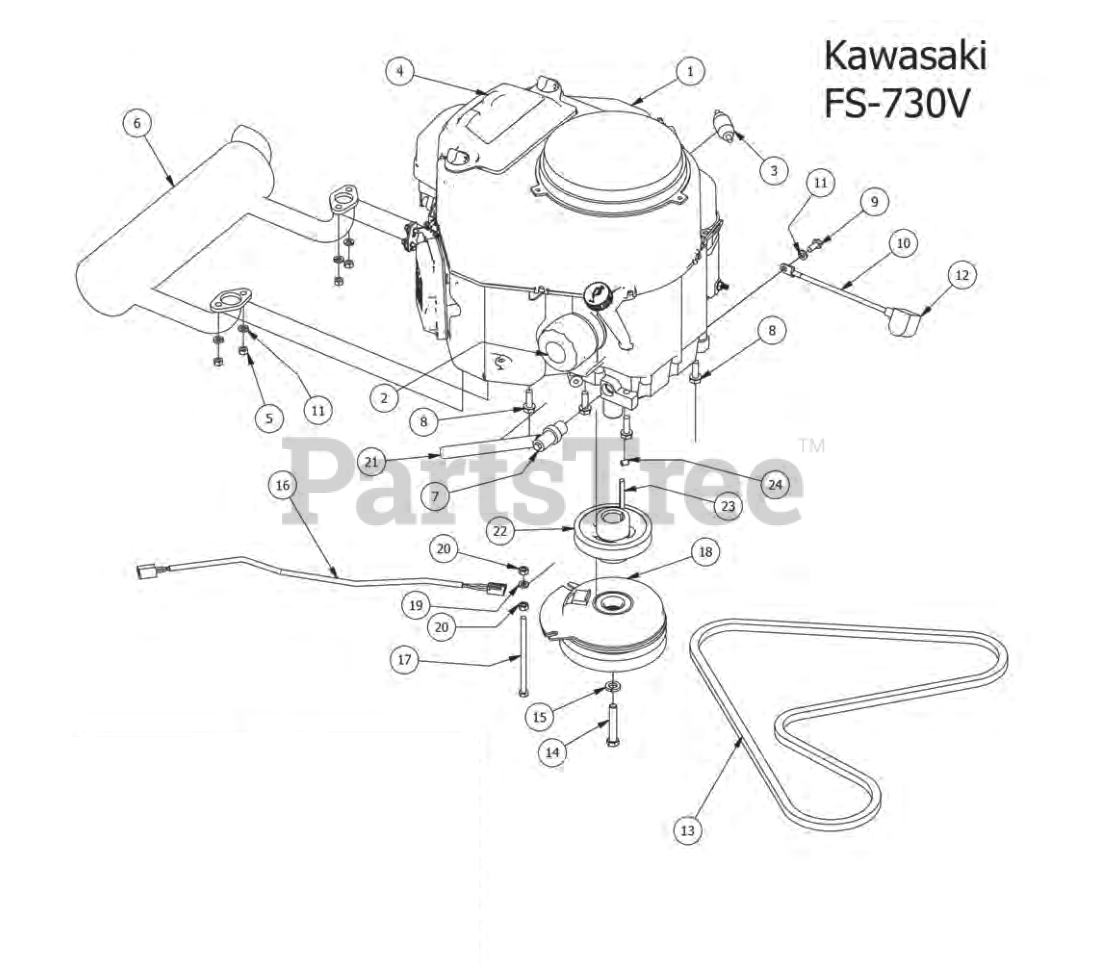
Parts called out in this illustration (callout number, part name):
1	FS730V Engine
2	Oil Filter
3	Universal inline Fuel Filter
4	Kaw air Filter For Engine
5	M8-1.25 Zinc Nut
6	Exhaust Kawasaki FS/FR-ZT/CZT
8	3/8 x 1 1/8 bolt
9	M8x1.20x20MM Hex head bolt
10	Starter to chassis cable
11	5/16" Lock Washer
12	Black Boot For ground cable
14	7/16" x 2 1/2" Hex Bolt
15	7/16" Lock Washer
16	Clutch Pigtail
17	5/16-18 x 5-1/2 GR 5 Hex Bolt
18	Clutch Assembly
19	5/16" Lock Washer
21	1/2 Clear Braded Hose Priced/Foot
22	4 3/4 Motor Pulley
23	1/4 x 2 Square key Stock
24	5/16 Set Screw
